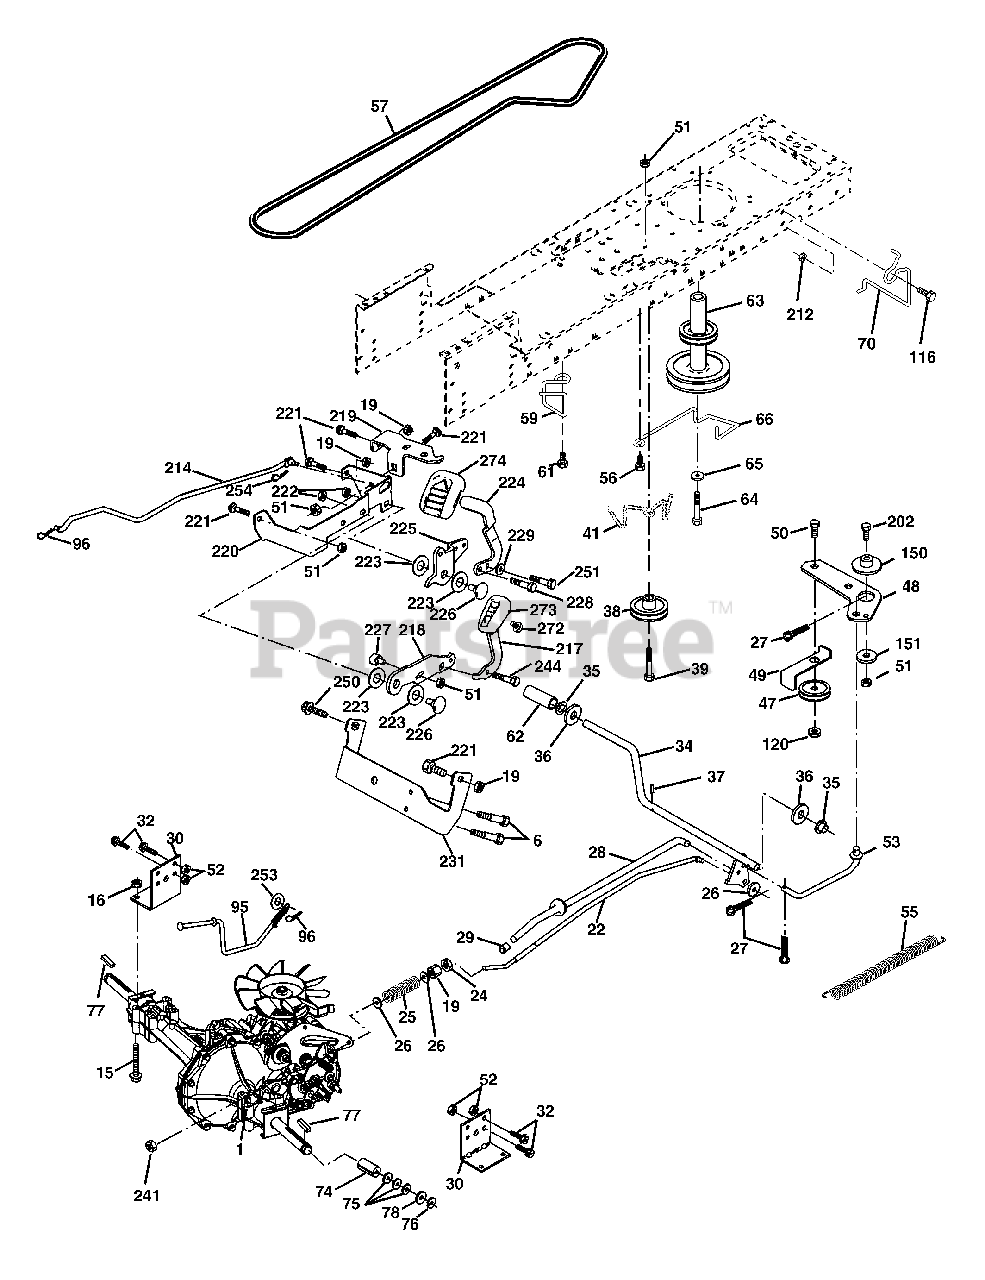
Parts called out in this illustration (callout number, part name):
6	Screw 5/16-18 x 3/4
9	Clutch Elec
15	Bolt Hex Flghd 5/16-18 Gr. 5
16	Nut Lock Hex W/Ins. 5/16-18 Unc
17	Washer 1-1/2 OD x 15/32 ID x .250
19	Nut Lock Hex W/Wsh 3/8-16 Unc
22	Rod, Brake
24	Nut, Hex Jam 3/8-16 Unc
25	Spring, Brake Rod
26	Washer
27	Pin Cotter 1/8 x 3/4 CAD.
28	Rod, Parking Brake
29	Cap, Brake, Park
30	Bracket, Transaxle
32	Bolt Hex Hd 5/16-18 Unc x 3/4
34	Shaft, Foot Pedal
35	Bearing, Nylon
36	Washer
37	Pin, Roll
38	Pulley, Composite, Flat
39	Bolt Fin Hex 3/8-16 Unc x 3
41	Keeper, Belt Idler Flat
47	Pulley, Idler, V-Groove
48	Bellcrank Clutch Grnd Drw Stl
49	Retainer, Belt
50	Bolt
51	Nut Crownlock 3/8-16 UNC
52	Nut, Crownlock 5/16-18 Unc
53	Link, Clutch
55	Spring, Return, Clutch
56	Screw 3/8-16 x 1-1/4
57	V-Belt, Ground Drive
59	Keeper, Center Span
61	Screw 3/8-16 x .875
62	Cover, Pedal
63	Pulley, Engine
64	Bolt Hex 7/16-20 x 4 x Gr. 5-1.5
65	Washer
66	Keeper Belt Engine
70	Guide Belt Mower RH
74	Spacer, Axle
75	Washer 25/32 x 1-1/4 x 16 Ga.
76	E-Ring
77	Key, Square
78	Washer 25/32 x 1-5/8 x 16 Ga.
95	Rod Bypass
96	Retainer Spring 1" Zinc/Cad
116	Bolt RDHD SQNK 3/8-16 Unc x 1
120	Nut Lock Flg 3/8-16 Unc
150	Spacer Retainer
151	Washer 13/32 x 2 x 10 Ga.
202	Bolt Carr Sh 3/8-16 x 1-3/4 Gr. 5
212	Nut Hex Flange Lock
214	Link Transaxle
217	Pedal Assy., Reverse with Pad
218	Arm Control Pedal Reverse
219	Bracket Frest Pdl Ctrl. Hyd
220	Bracket Mtg. Pedal Control
221	Bolt Rdhd Sqnk 3/8-16 Unc x 3/4
222	Nut Crownlock 7/16-14 Unc
223	Washer Nylon 11/16 ID x .060
224	Pedal Forward
225	Arm Control Pedal Forward
226	Bolt Pivot Spacer
227	Cam Reverse Pedal LT
228	Bolt Shoulder 5/16-18
229	Washer Serrated 5/16 x .75
231	Strap Torque
241	Nut Centerlock 1/4-20 Unc
244	Screw 5/16-18 x 5/8
250	Screw 3/8-16 x .75
251	Screw 5/16-18 x 1
253	Washer .3125 x .615 x 16 Ga.
254	Clip Retainer
272	Screw 5/16-18 x 1/2 TT
273	Pad, Reverse Pedal
274	Cover Pedal Forward
